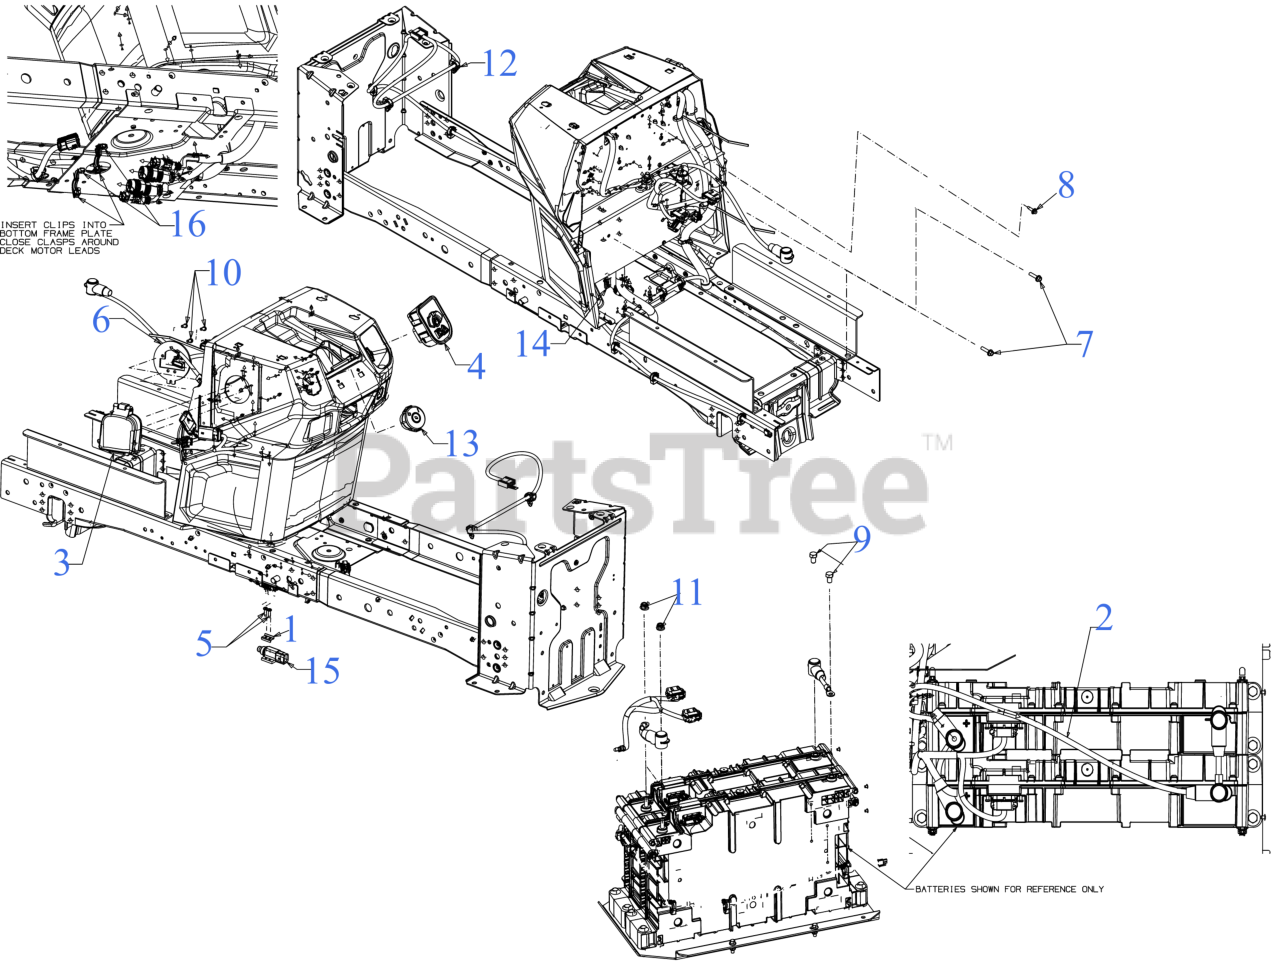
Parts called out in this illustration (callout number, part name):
1	PLATE-SWITCH
2	MOTOR CONTROL PANEL
3	LI-ION CHARGE PORT ASSEMBLY
4	VCM MODULE
5	SCREW #
6	CHARGE PORT MOUNTING PLATE
7	SCREW 1/4-20 x 1.0
8	SCREW 1/4-10 x .750
9	SCREW 3/8-24 x .50" GR5 STD
10	SCREW #12-16 x .625
11	FLANGE LOCK NUT 5/16-18
12	HARNESS (VCM HPD BATTERY)
13	KEY SWITCH (2 POSITION)
14	U-CLIP NUT
15	SEALED PLUNGER SWITCH
16	CONDUIT CLIP (DELPHI)
